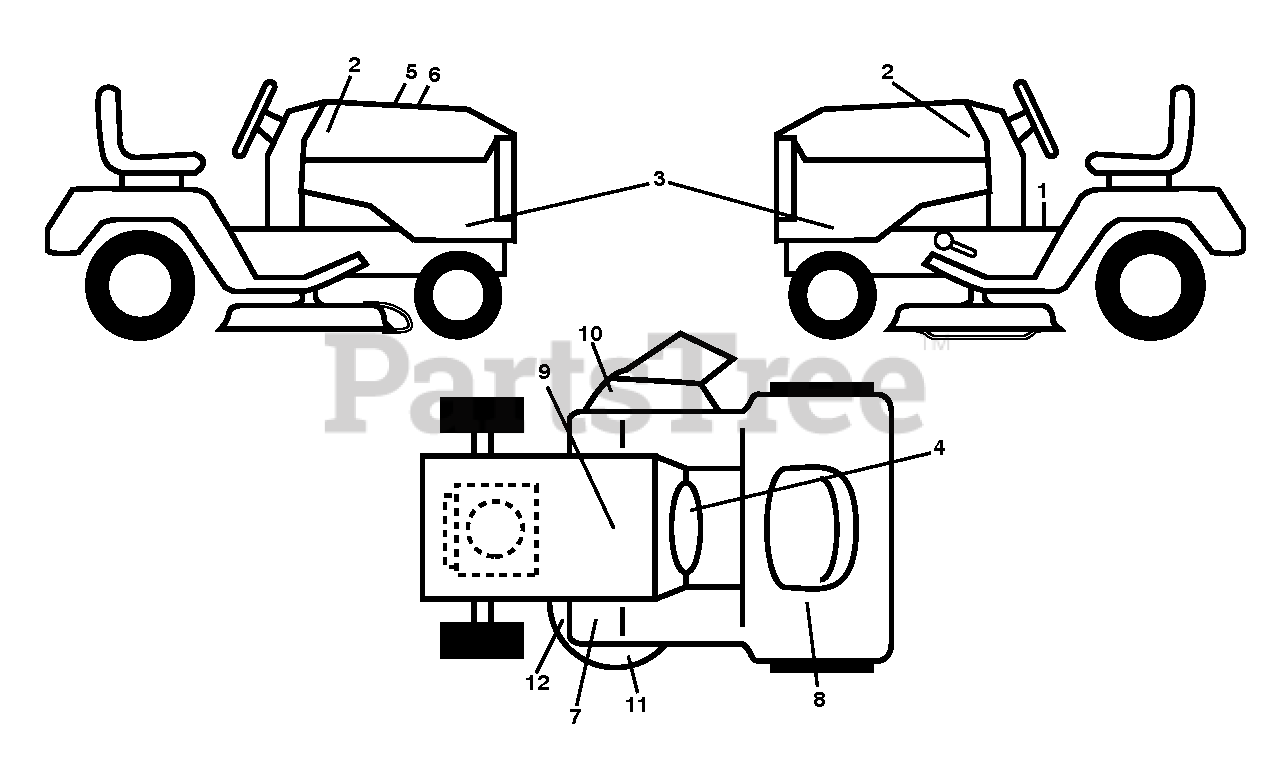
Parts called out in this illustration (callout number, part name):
1	DECAL.FENDER.WARNING
2	RP.DECAL.BADGE.170MM.TEXTLOGO
3	DECAL.SDPNL.HUSQGT2.MS668.YTH2
4	DECAL, WARNING SPARK ARRESTOR
5	DECAL.WARNING.CUST.RESP.E85.
7	DECAL.PEDAL.HUSQ.CROWN
8	DECAL.WARN.RESERVE.FUEL
9	DECAL BTRY SYMBOLS
10	DECAL, NO STEP
11	DECAL, CAUTION
12	DECAL.MOWER.SCH.48/54
